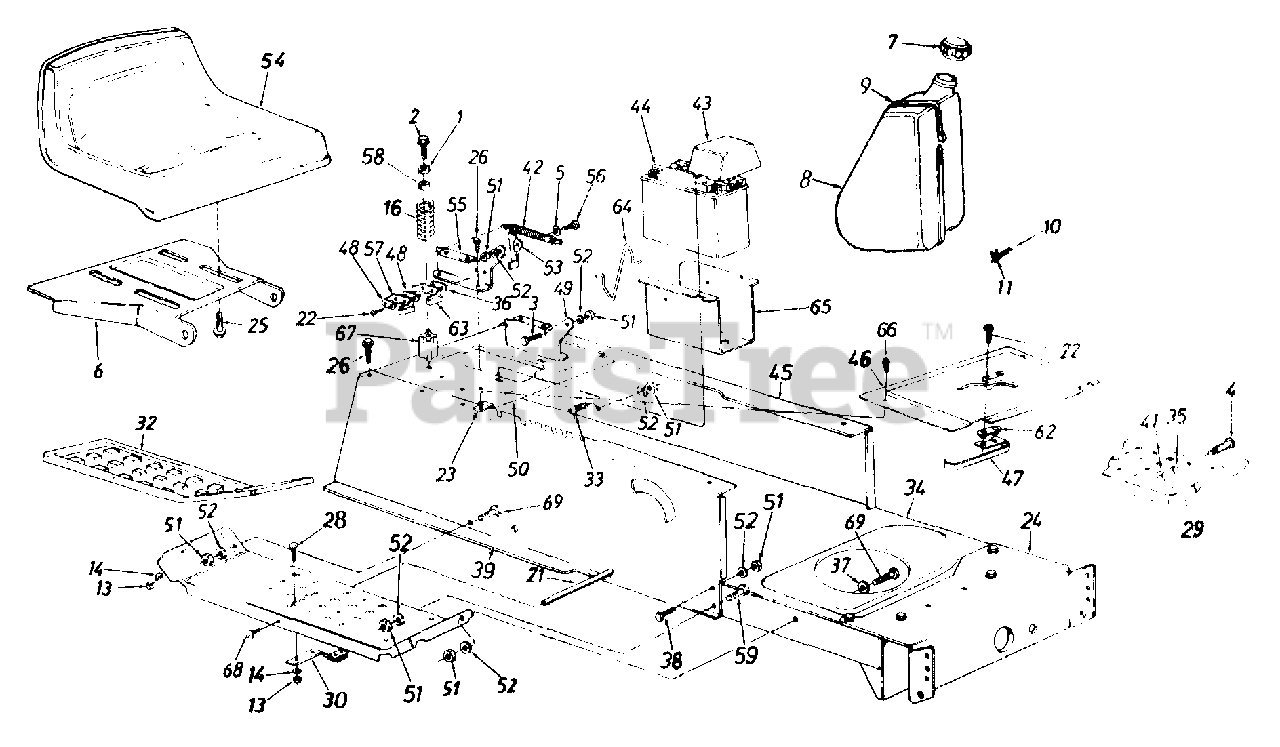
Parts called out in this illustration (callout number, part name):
1	Fl-Wash. .344" I.D. x .875"
2	Hex Wash. Hd. Tap Scr. 5/16-18 x 3.25" Lg.
3	Shld. Bolt .437" Dia. x .162"
4	Shld. Bolt .50" Dia. x .84"
5	Spr-Wash. .445" I.D. x .75
7	Fuel Cap
8	Fuel Tank
9	Tie Strap
10	Fuel Line
11	Hose Clamp
13	Hex Nut 1/4-20 Thd.
14	L-Wash. 1/4" I.D.
16	Compression Spring
21	Running Board Rod
22	Hex Wash. Hd. AB-Tap Scr. #8 x .50" Lg.
23	Speed Nut #10Z
24	Front Pivot Brkt.
25	Hex Tap Scr. 3/8-16 x .75"
26	Hex Wash. Hd. AB-Tap Scr. 5/16 x .75" Lg.
28	Carriage Bolt 1/4-20 x .62"
29	Running Board (R.H. & L.H.)
30	Blade Brake Ass'y.
32	Rubber Foot Pad - L.H.
33	Truss Mach. Scr. 5/16-18 x .75" Lg
34	Lower Frame
35	L-Wash. 3/8" I.D.
36	Insulator Boss Plate
37	Fl-Wash. .344" I.D. x .625" O.D.
38	Hex Bolt 5/16-18 x .75" Lg.
42	Extension Spring 5.31" Lg.
43	Battery Cover
44	12-V Battery
45	Upper Frame - L.H.
46	Shift Cover
47	Reverse Safety Switch
48	Insulator Plate
52	L-Wash. 5/16" I.D.
53	Seat Lift Brkt.
56	Shld. Bolt .437" Dia. x .268"
57	Spring Switch
59	Hex Wash. TT-Tap Scr 5/16-18 x 7/8" Lg
62	Insulator Nut Plate
63	Safety Switch (Seat)
64	Battery Tray Clip
65	Battery Tray
66	Truss Mach. B-Tap Scr. #10 x .5" Lg.
67	Spring Spacer
68	Pan Hd. Cutting Scr. 5/16-18 x .75" Lg
69	Hex Bolt 5/16-18 x .75" Lg.
